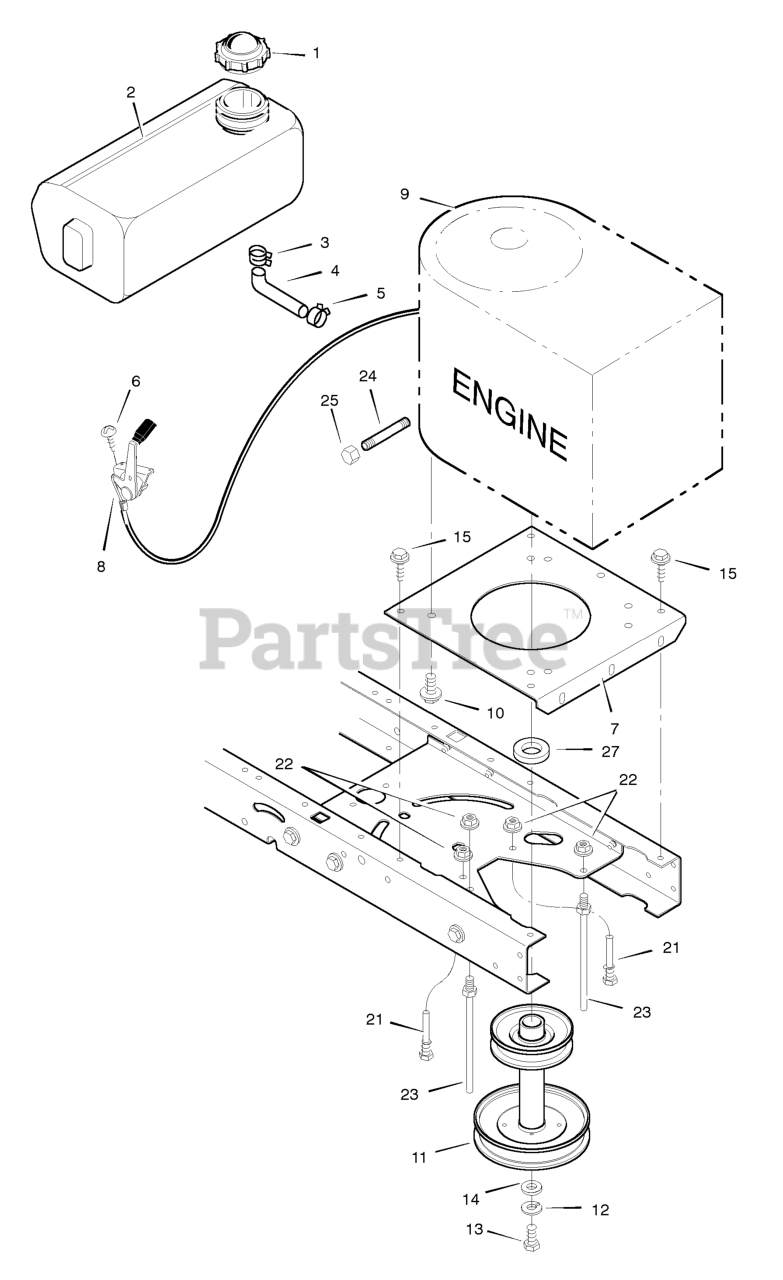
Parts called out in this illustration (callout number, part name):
1	Fuel Cap
2	Fuel Tank
3	Hose Clamp
4	Fuel Line
5	Hose Clamp
7	Plate, Engine
8	Throttle Control
9	Engine *
10	Bolt, Engine Mount
11	Stack Pulley Assembly
12	Lockwasher
13	Bolt, Hex
21	Guide, Belt
22	Nut, Flange
23	Guide, Belt
24	Pipe, Oil Drain
25	Cap, Oil Drain
